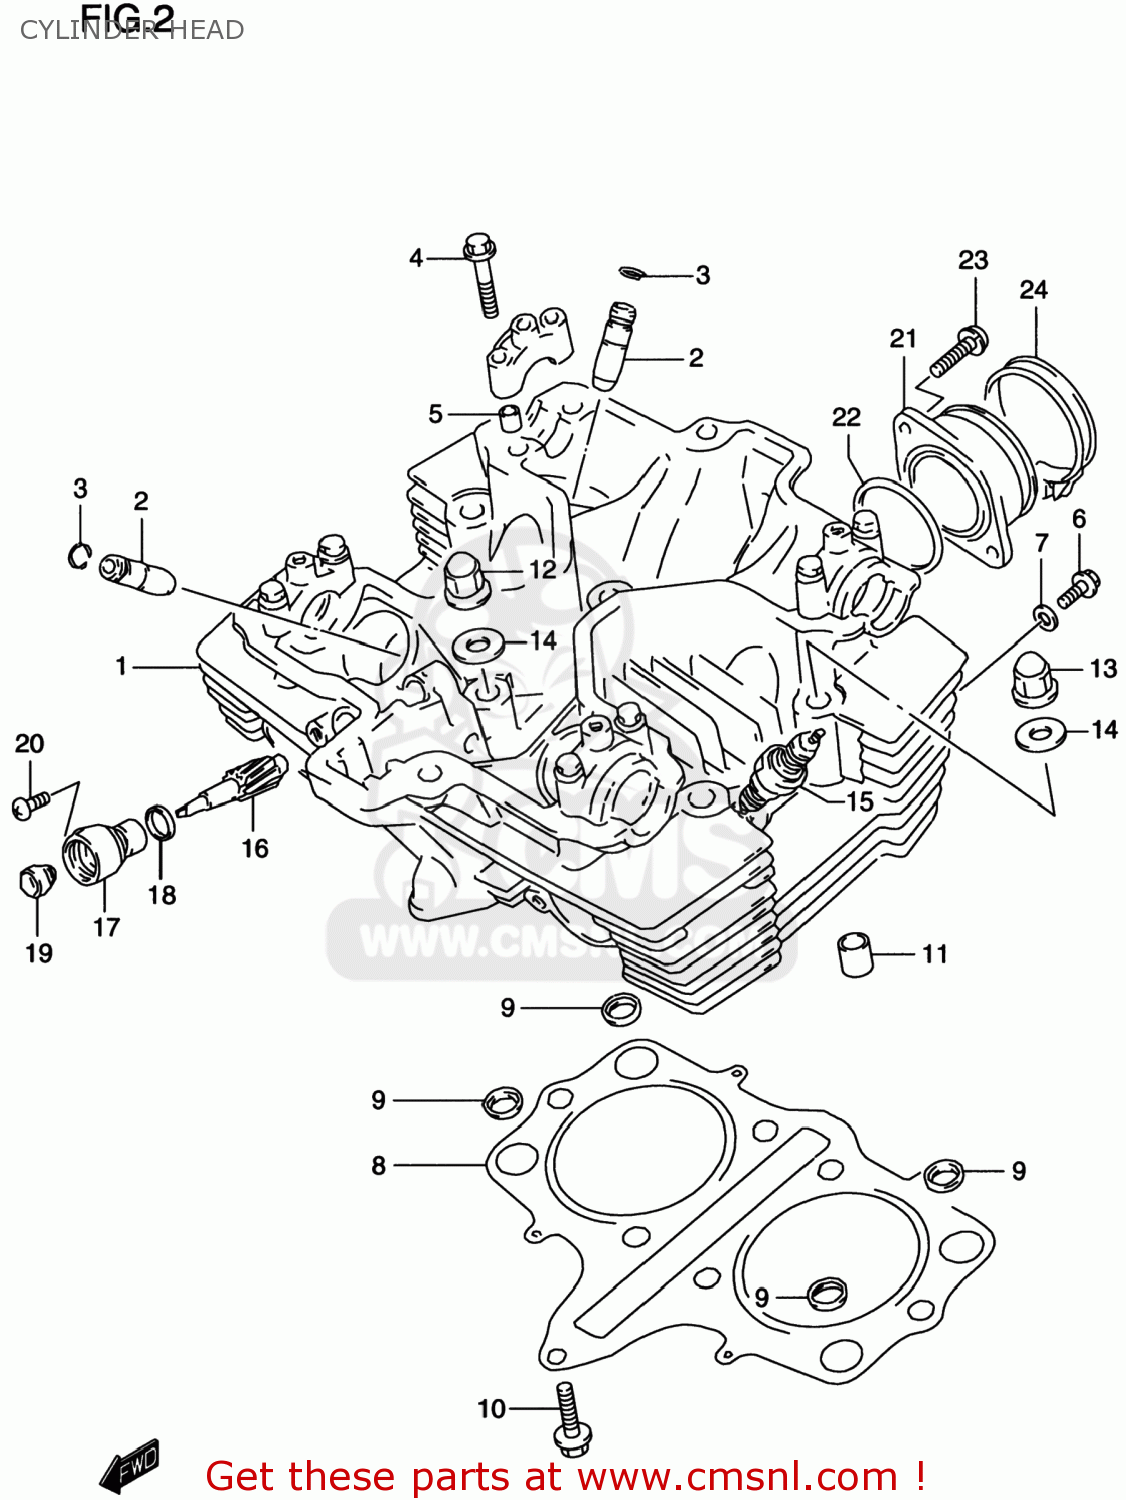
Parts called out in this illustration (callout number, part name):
1	HEAD ASSY,CYLINDER
2	GUIDE,INTAKE VALVE
3	RING,SNAP
4	BOLT(6X39)
5	PIN(6.2X8X11)
6	BOLT
7	GASKET(5.8X13X1.2) (NAS)
8	GASKET,CYLINDER HEAD (NAS)
9	O RING,HEAD GASKET
10	BOLT
11	PIN
12	NUT
13	NUT
14	GASKET(10.2X20X2).3 (NAS)
15	PLUG,SPARK(DPR8EA-9)
16	GEAR,TACHOMETER DRIVEN
17	SLEEVE,TACHOMETER DRIVE GEAR
18	SEAL,TACHOMETER DRIVEN
19	SEAL,OIL(5X12X8)
20	SCREW(5X12)
21	PIPE,INTAKE
22	O RING(D:2.4,ID:39.7)
23	SCREW
24	CLAMP
